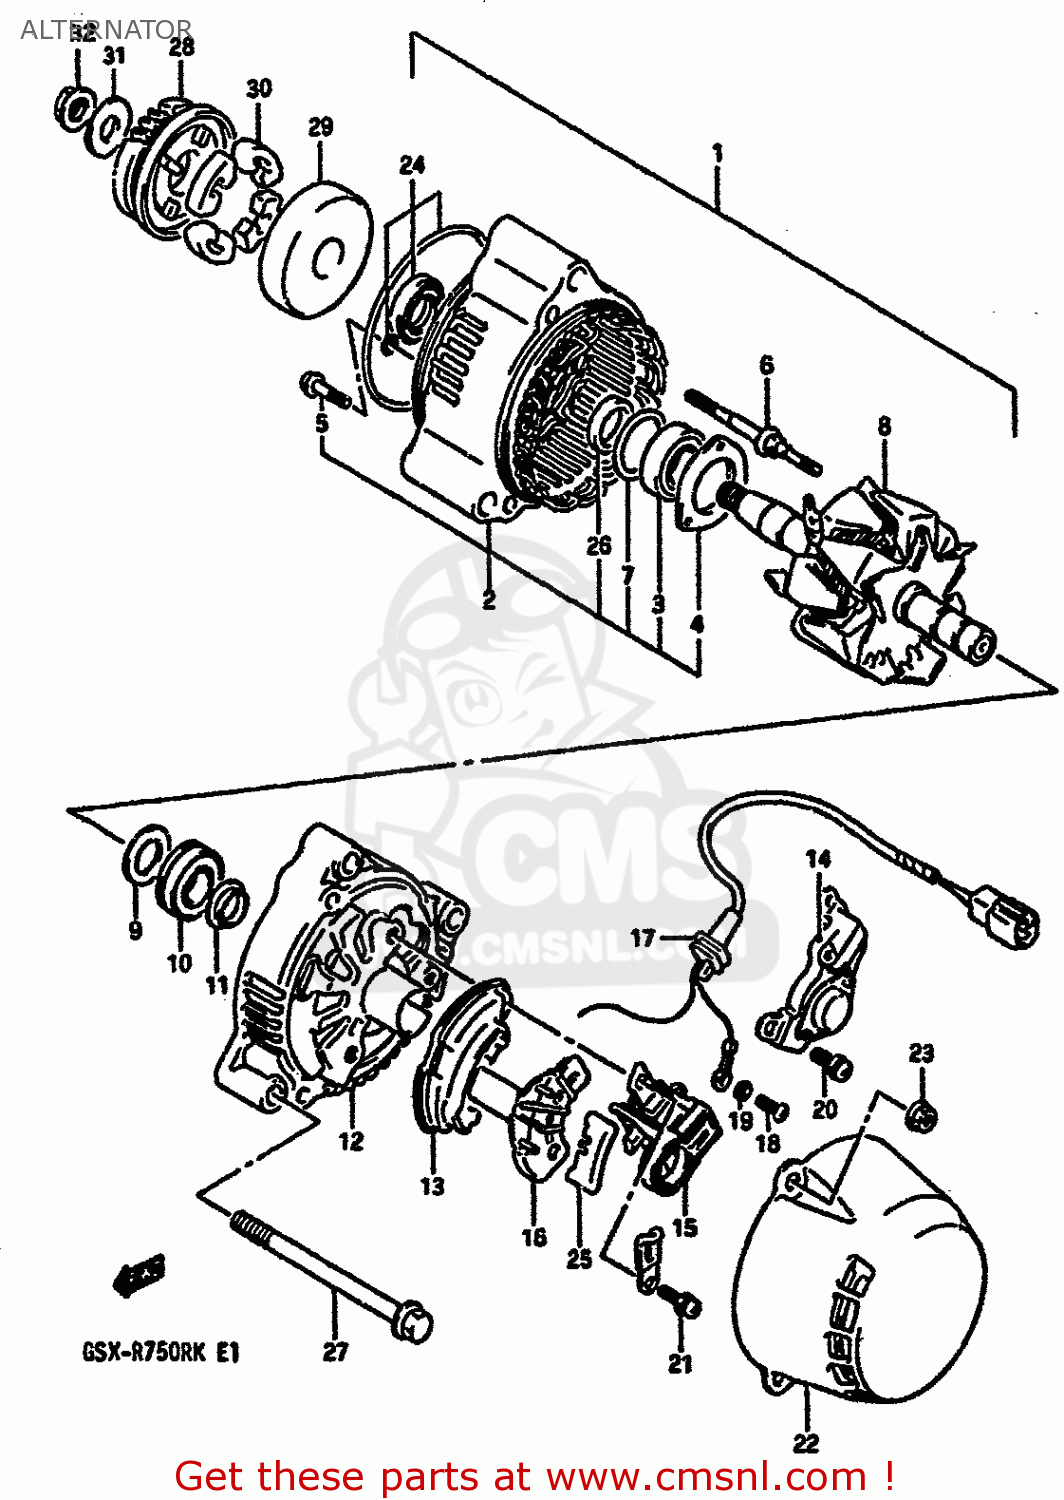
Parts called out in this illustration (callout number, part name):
1	GENERATOR ASSEMBLY
2	FRAME,DRIVE END
3	BEARING
4	RETAINER
5	SCREW,BEARING RETAINER
6	STUD BOLT
7	COVER,BEARING
8	ROTOR ASSEMBLY
9	COVER (2)
10	BEARING
11	COVER(2)
12	FRAME,END
13	HOLDER,RECTIFIER
14	REGULATOR
15	HOLDER,BRUSH
16	COVER,RECTIFIER
17	WIRE,LEAD
18	SCREW
19	LOCK WASHER
20	SCREW
21	SCREW
22	COVER
23	NUT ,5MM
24	SEAL SET,OIL
25	BUSH
26	SPACER
27	BOLT (8X90)
28	GEAR,GENERATOR DRIVEN
29	HOUSING,GENERATOR GEAR
30	DAMPER,GENERATOR DRIVEN
31	WASHER
32	NUT
